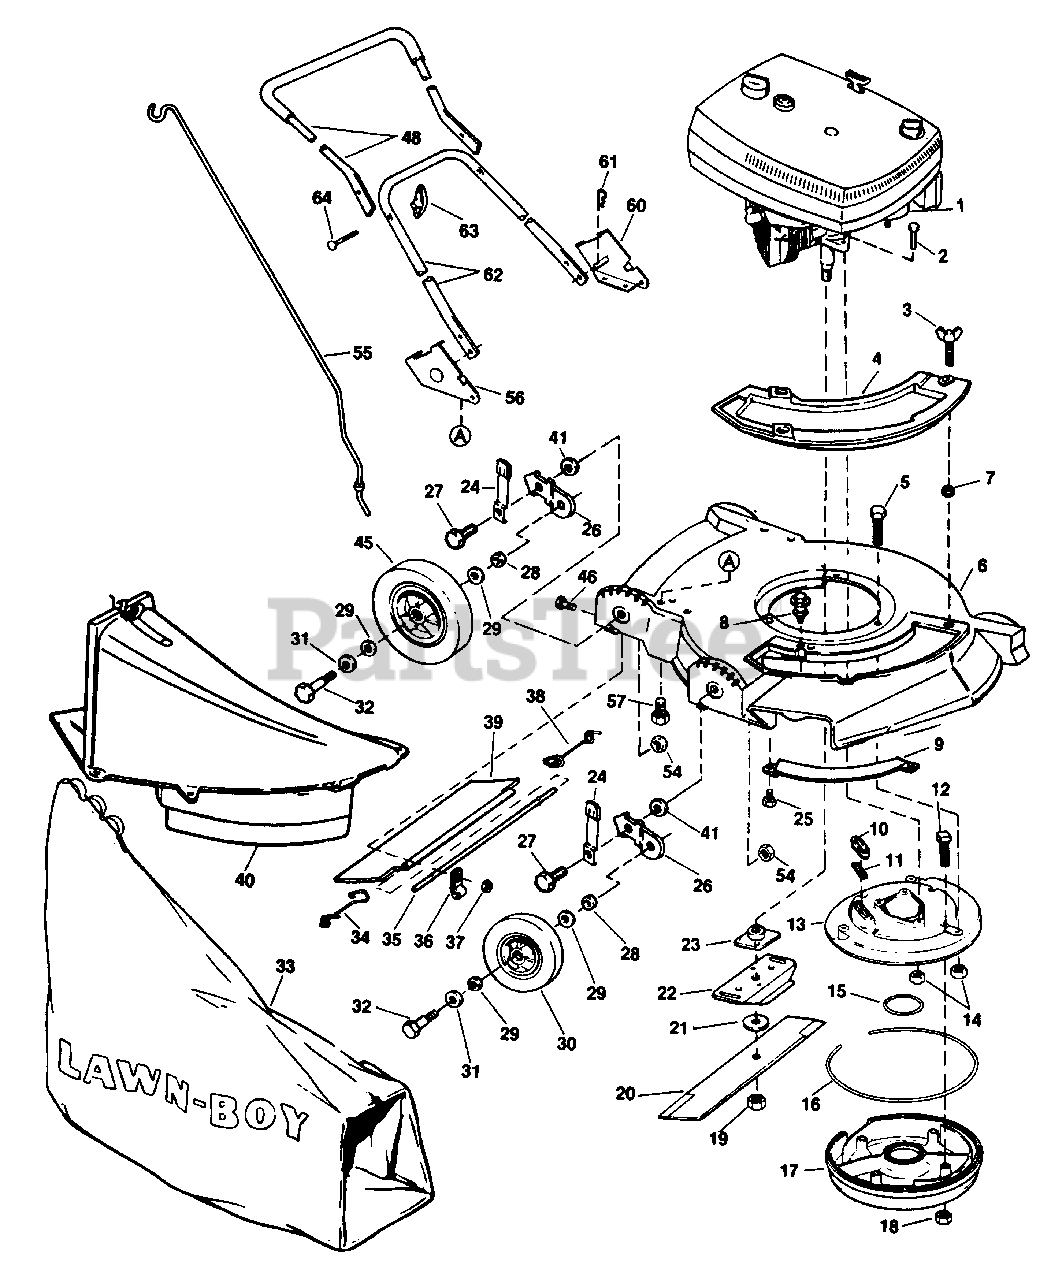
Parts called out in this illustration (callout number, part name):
1	See Page 30 for Engine, Magneto and Carburetor Parts List. See Note #2 at bottom of this page.
2	Screw-Crankcase to Muffler Plate
3	Wing Screw
4	Cover Plate
5	Screw-Muffler Plate to Housing
6	19" Housing
6	21" Housing
7	Grommet
8	Shoulder Screw
9	Toe Bar
10	Sleeve-Muffler Gasket
11	Gasket-Exhaust
12	Screw-Muffler to Muffler Plate
13	Muffler Plate
15	Gasket-Muffler (inside)
16	Gasket-Muffler (outside)
17	Muffler Cover
18	Nut-Muffler to Muffler Plate
19	Nut-Blade
20	Blade-19"
20	Blade-21"
21	Blade Washer-21" Models Only
22	Stiffener-Blade
23	Collar and Plate Assembly
24	Knob & Spring Ay.
25	Screw
26	Wheel Hgt. Adj. Brkt.
27	Screw
29	Felt Washer
30	Wheel and Tire-6"
33	Bag Assembly
34	Spring-R.H.
35	Rod
38	Spring-L.H.
39	Shield
40	Chute Assembly
41	Washer-Wheel Brkt. Mtg.
45	Wheel and Tire-8"
48	Handle-Top Section
55	Rod-Grass Bag
56	Bracket & Pin Assy.-R.H.
57	Screw
60	Bracket & Pin Assy.-L.H.
61	Clip-Hair Pin
62	Handle-Bottom Section
64	Screw
